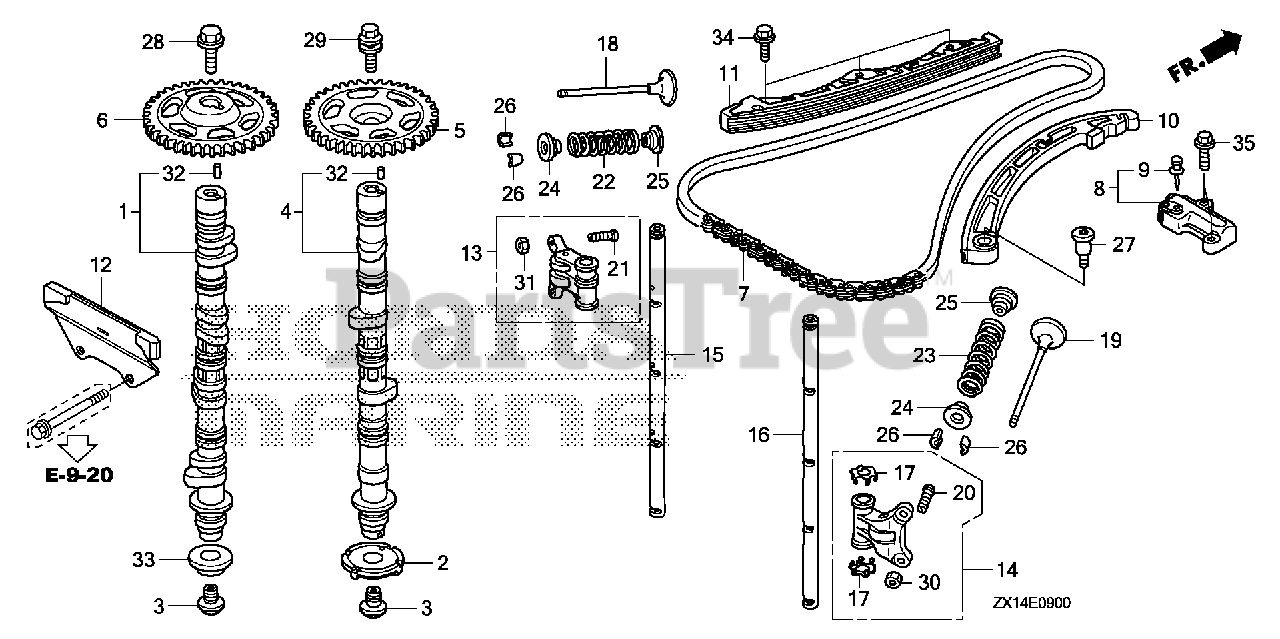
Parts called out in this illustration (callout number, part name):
1	CAMSHAFT, IN.
2	PLATE, TDC PULSE
3	BOLT, SEALING (14MM)
4	CAMSHAFT, EX.
5	SPROCKET, CAM CHAIN DRIVEN (46T)
6	SPROCKET, CAM CHAIN DRIVEN IN. (46T)
7	CHAIN (176L) (DAIDO)
8	TENSIONER ASSY., CAM CHAIN
9	STOPPER (TOOL)
10	ARM, CAM CHAIN TENSIONER
11	GUIDE, CAM CHAIN
12	GUIDE B, CAM CHAIN
13	ARM ASSY., ROCKER
14	ARM ASSY., EX. ROCKER
15	SHAFT, IN. ROCKER
16	SHAFT, EX. ROCKER
17	WASHER, THRUST
18	VALVE, IN.
19	VALVE, EX.
20	SCREW, TAPPET ADJUSTING
21	SCREW, TAPPET ADJUSTING
22	SPRING, IN. VALVE (PINK) (NIPPON HATSUJO)
23	SPRING, EX. VALVE (GRAY) (NIPPON HATSUJO)
24	RETAINER, VALVE SPRING
25	SEAT, VALVE SPRING
26	COTTER, VALVE (FUJI VALVE)
27	BOLT, TENSIONER PIVOT
28	BOLT, FLANGE (12X47)
29	BOLT, FLANGE (10X32)
30	NUT, TAPPET ADJUSTING (TOKAI TRW)
31	NUT, TAPPET ADJUSTING
32	PIN, DOWEL (4.2X10.3)
33	COLLAR, CAMSHAFT
34	BOLT, FLANGE (6X20)
35	BOLT, FLANGE (6X30)
